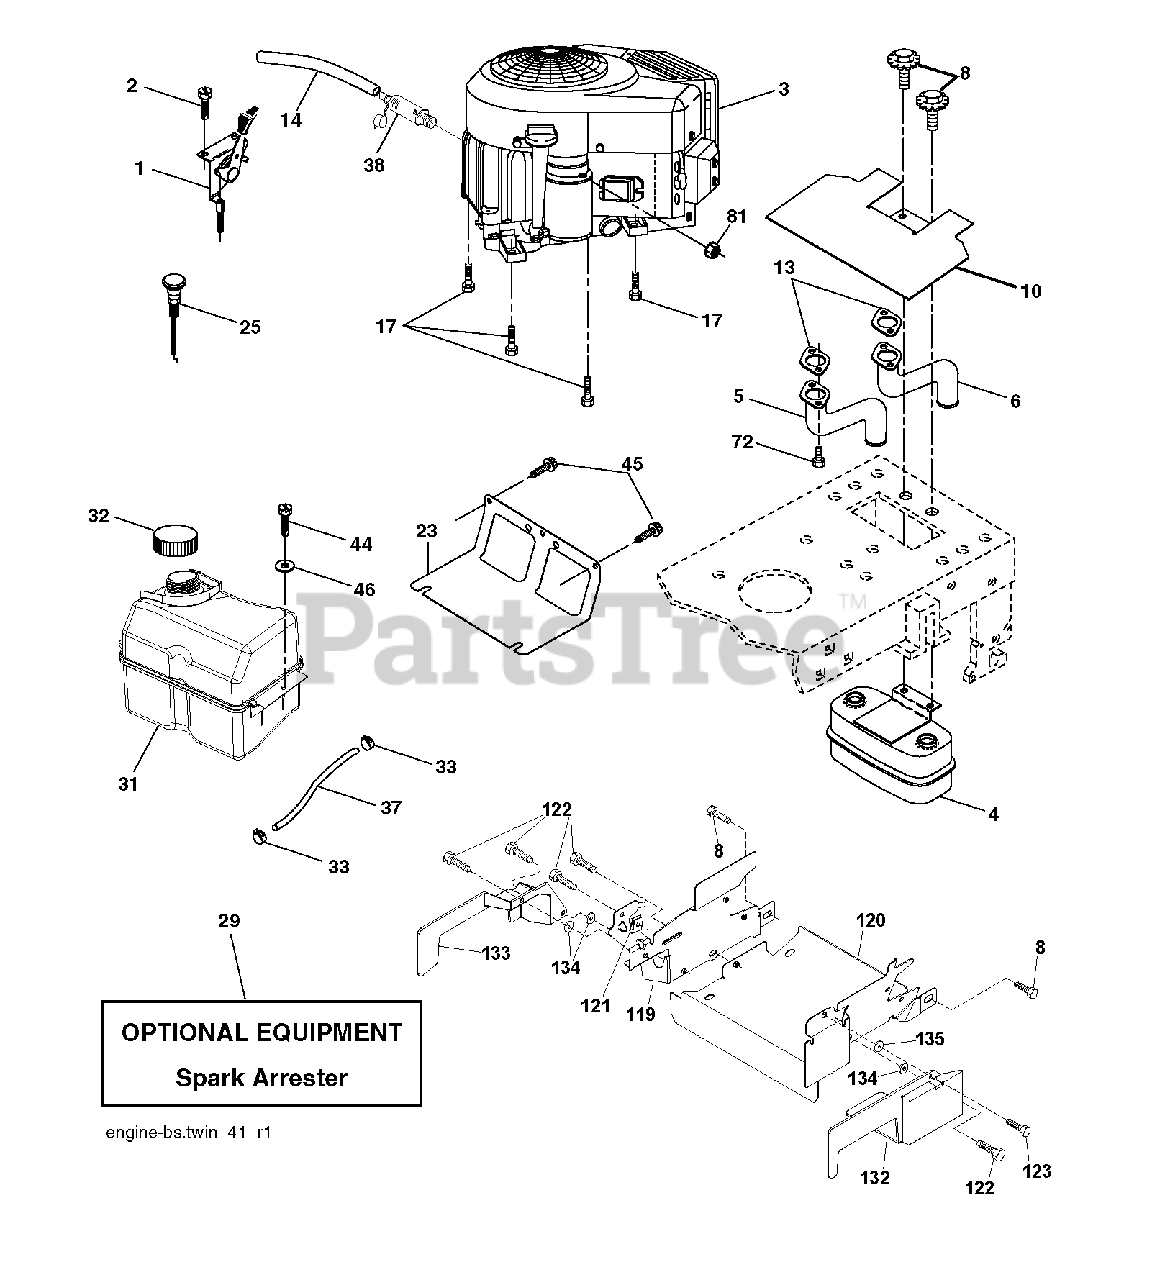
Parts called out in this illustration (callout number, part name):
1	THROTTLE CABLE
2	SCREW.#10 X 0.750.BOS THREAD
4	MUFFLER.TWIN.CYL.LOW.TONE
5	EXHAUST TUBE RH
6	TUBE MANIFOLD LH
8	BOLT, 5/16-18 X 1 3/4
10	RP SHIELD HEAT MUFFLER
13	GASKET.MUFFLER
14	TUBE, DRAIN OIL ASM.
17	SCREW.3/8-16
23	SHEILD.BROWNING.DBR.GUARD
25	CONTROL CHOKE
29	ARRESTER SPARK (OPTIONAL)
32	FUEL CAP
33	HOSE CLAMP
37	LINE.FUEL.20
38	PLUG DRAIN OIL EASY
44	SCREW HEXWSHR 1/4-20X3/4
45	SCREW, 3/8-16X3/4
72	SCREW.SOCKET.HEAD.5/16-18
81	NUT
122	SCREW.1/4-20X5/8
123	SCREW, 5/16-18 X 1/2
134	PALNUT 1/4
